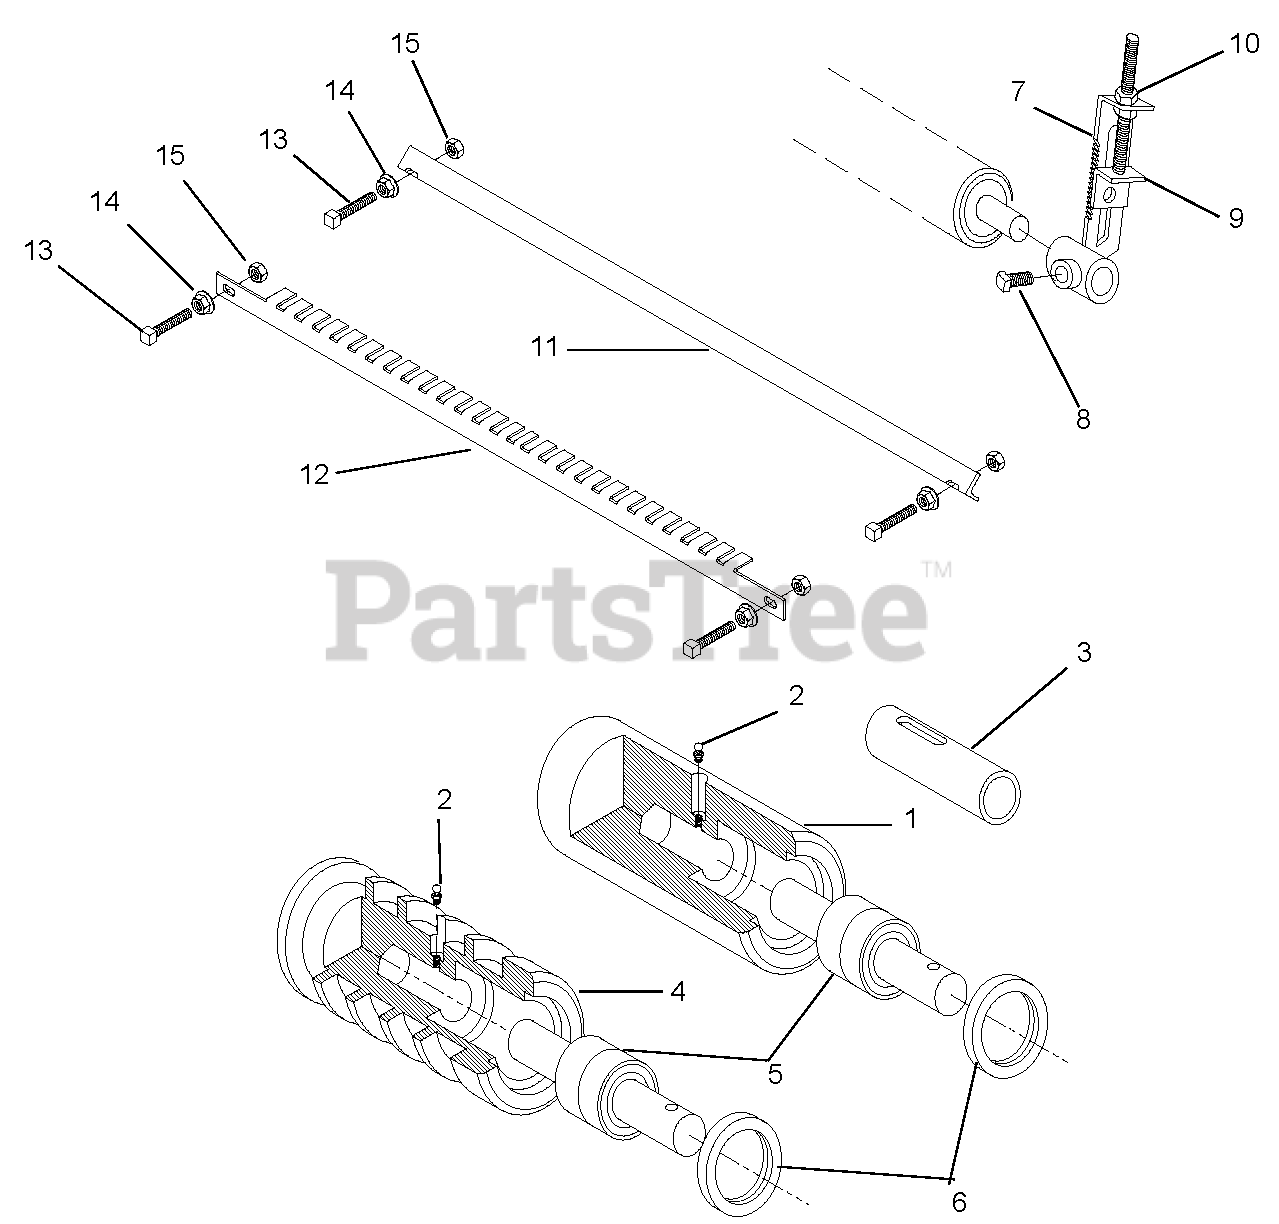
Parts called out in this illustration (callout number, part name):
1	Roller (Only), Smooth Aluminum 3-Inch
2	Fitting, Grease
3	Bushing, Adapter
4	Roller (Only), Grooved Aluminum 3-Inch
5	Bearing Assembly, Integral Bearing
6	Seal, Oil
7	Weldment, Roller Bracket Right Hand
8	Set Screw, Square Head .375 x .75 SAE 8
9	Weldment, Adjuster Roller
10	Nut, Hex .375-165 CP
11	Scraper, Smooth Roller
12	Scraper, Grooved Roller
13	Set Screw, Square Head Cup Point .375 x 2.25
14	Nut, Hex Lock Serrated Flange .375-16
15	Nut, Hex .375-24 NF
